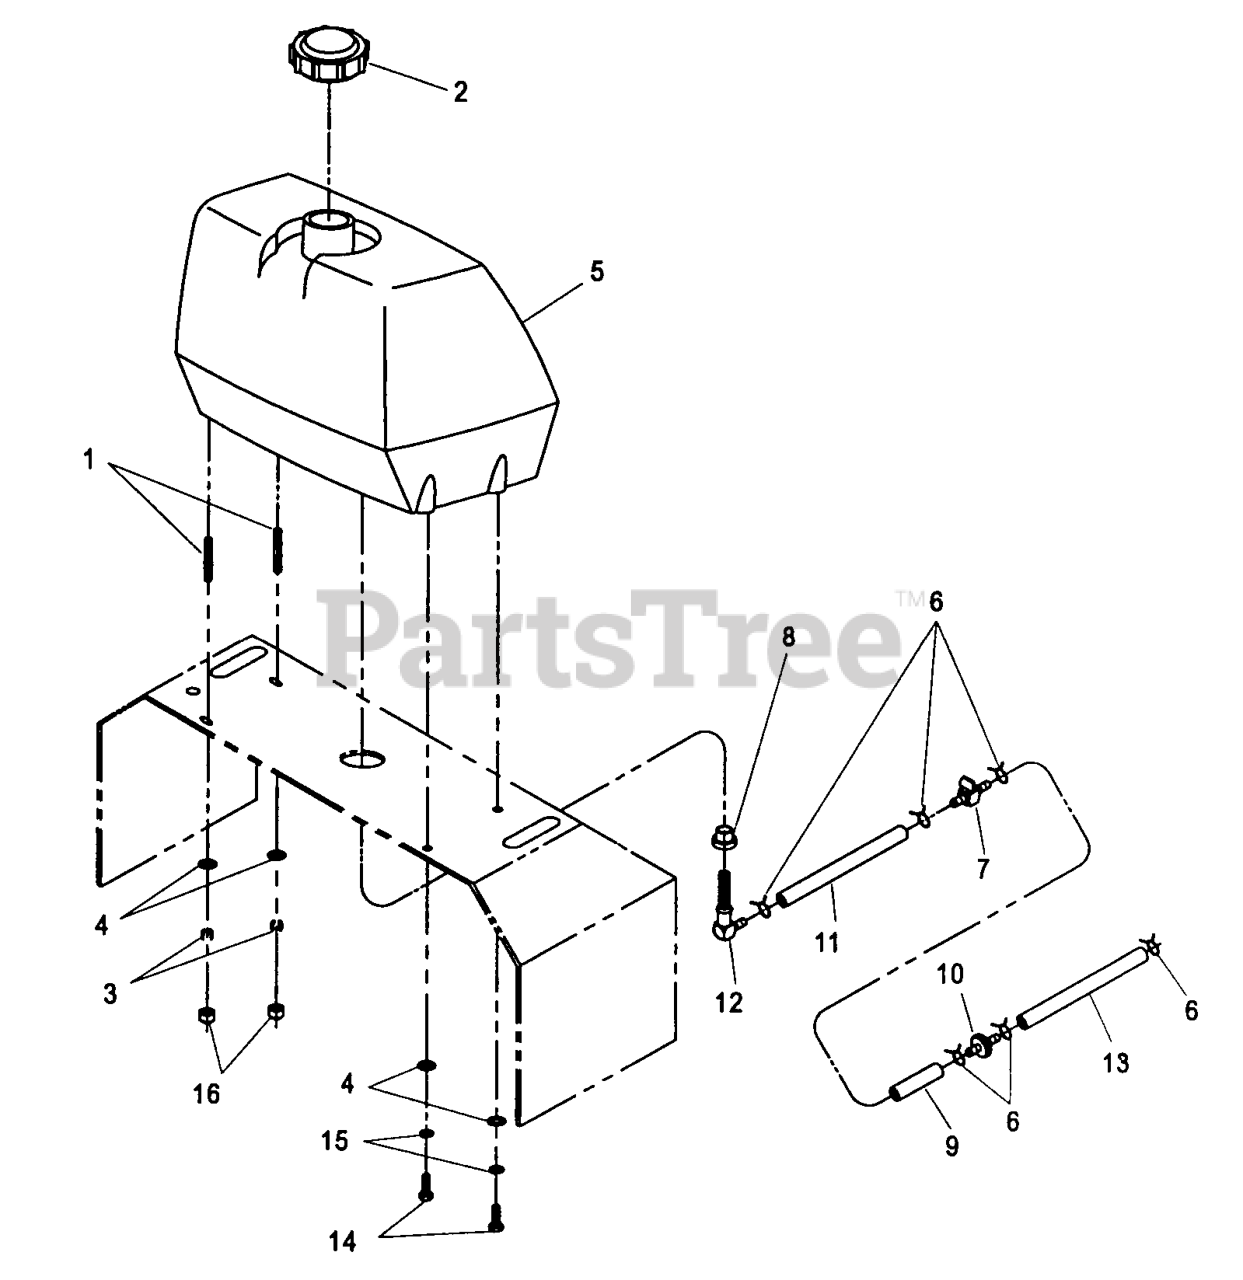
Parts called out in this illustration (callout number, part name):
1	STUD
2	CAP-FUEL
3	SPRING-TANK, FUEL
7	VALVE-FUEL
9	HOSE-LINE, FUEL
12	ELBOW-TANK, FUEL
15	WASHER-LOCK
